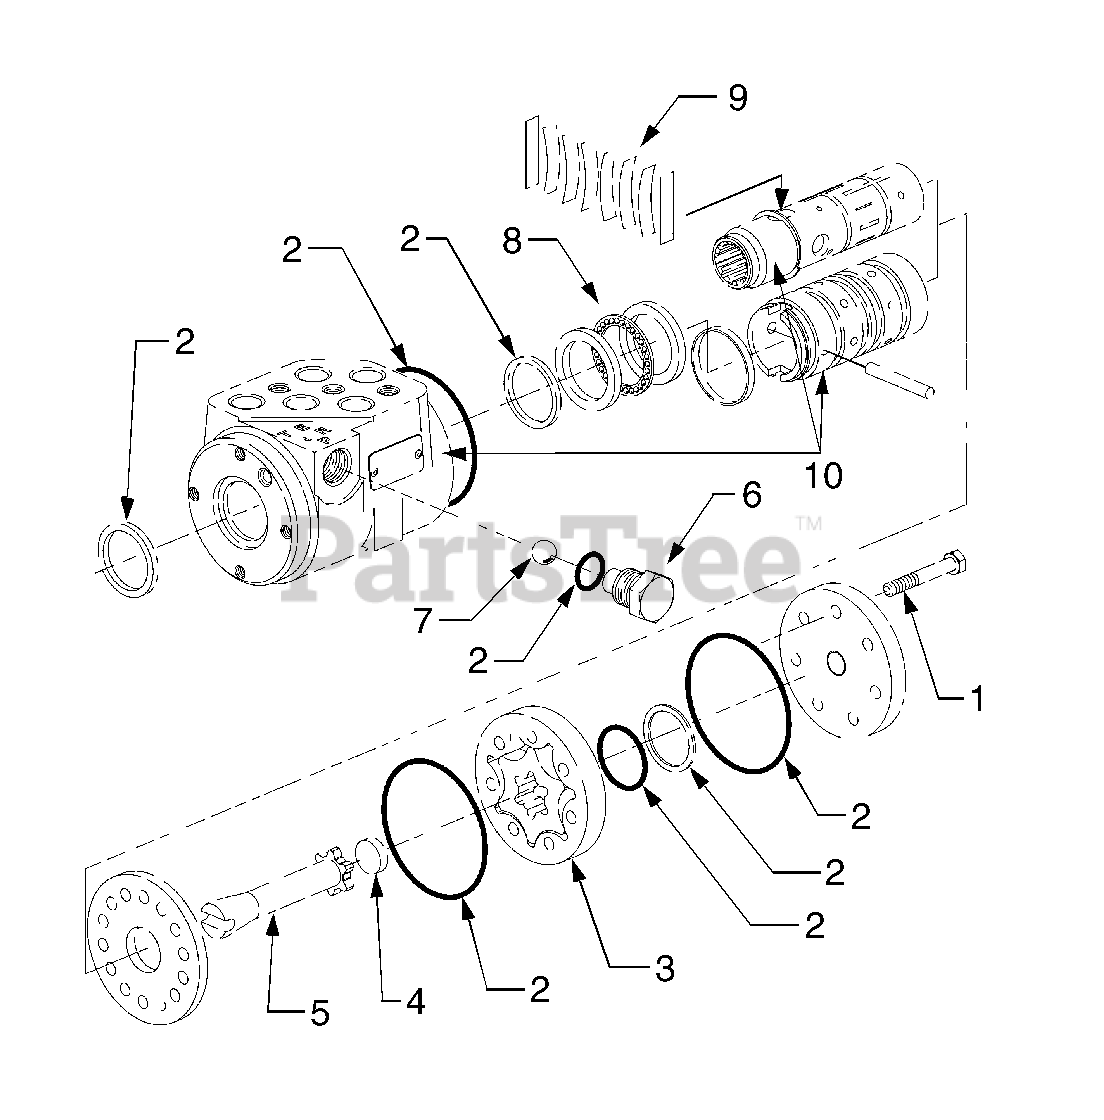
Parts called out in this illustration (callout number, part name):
1	Screw, Hex Cap, 1.57" Lg.
2	Seal Kit
3	Gerotor Assembly
4	Spacer, .240 Lg.
6	Plug, Manual Check
7	Ball, Manual Check
9	Spring Kit, Centering
10	Spool, Sleeve and Housing
